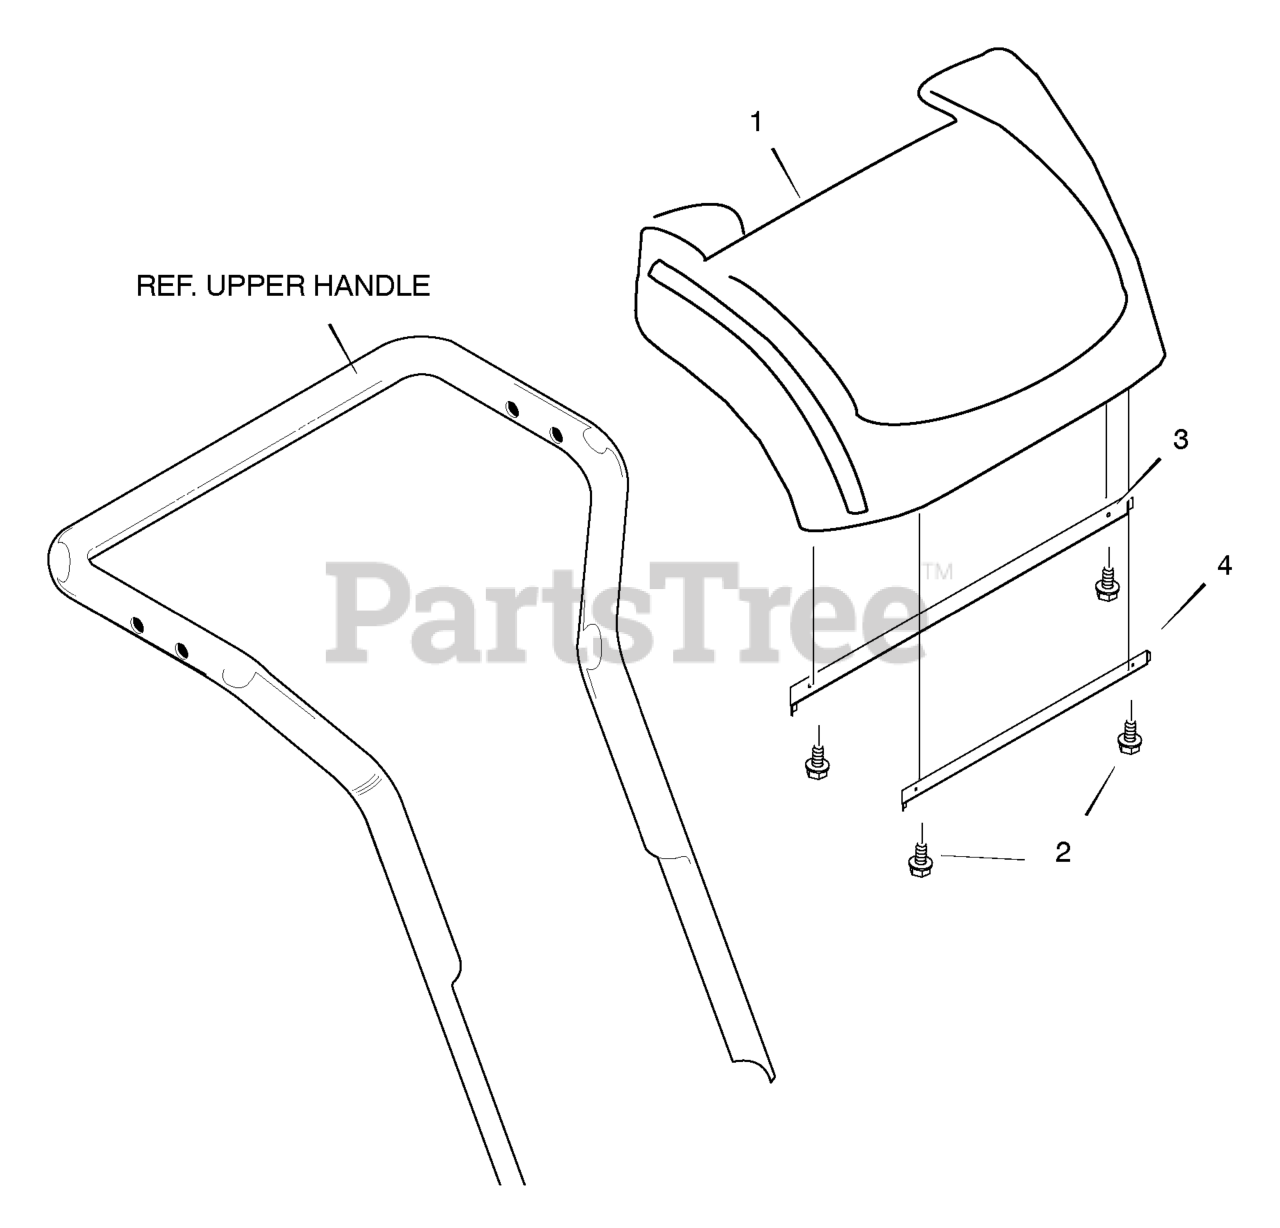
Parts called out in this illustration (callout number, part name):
1	PANEL, CONSOLE
2	SCREW, 10 x 0.62
3	BRACKET, HANDLE COVER -TOP
4	BRACKET, HANDLE COVER -BOTTOM
